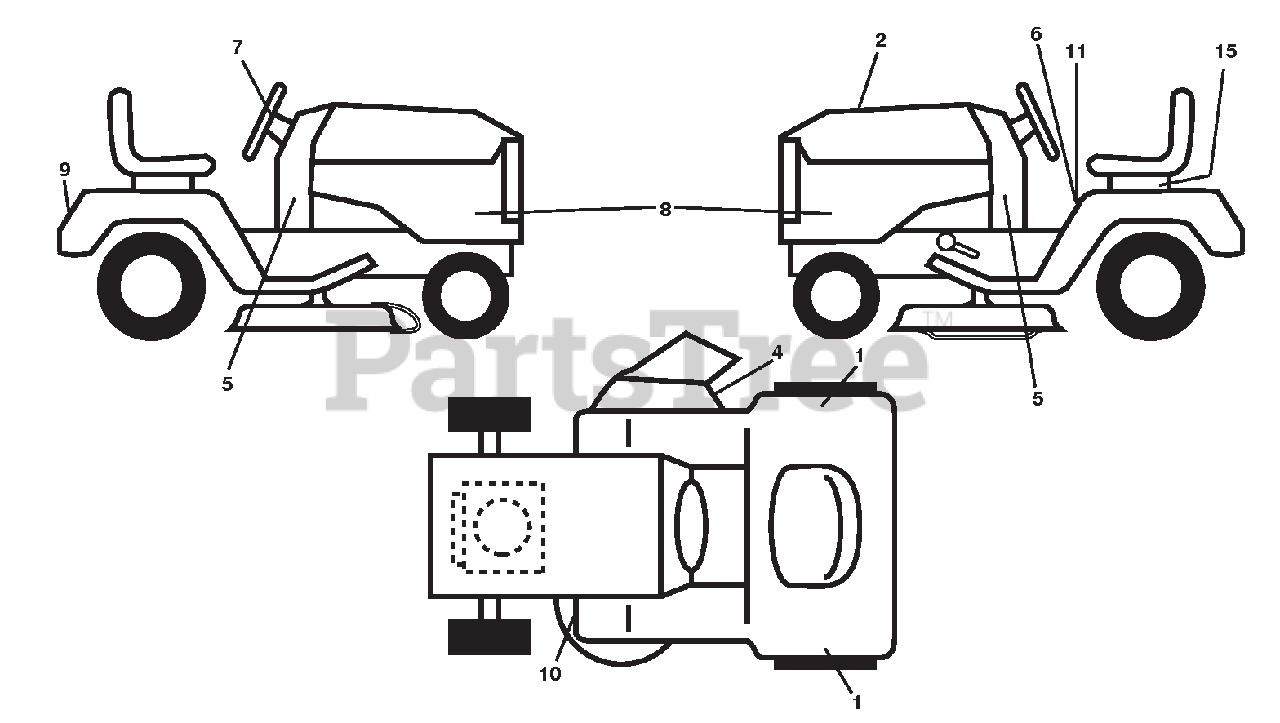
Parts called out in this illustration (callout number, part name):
1	DECAL.FENDER.SIDE.HYDRO
2	DECAL, REPLACEMENT
4	DECAL.WARNING.KEEP.HAND.AWY
5	DECAL, DASH.LOWER
6	DECAL, FENDER.WARNING
7	DECAL.WHEEL.STEER.ARIENS
8	DECAL.SDPNL.PWRDBY KOHL.ARIENS
9	DECAL.FENDER.REAR.ARIENS
10	DECAL.V-BELT.SCH.
11	DECAL.FENDER
15	DECAL.BAT.DAN/POI P/L SYM.WPN
